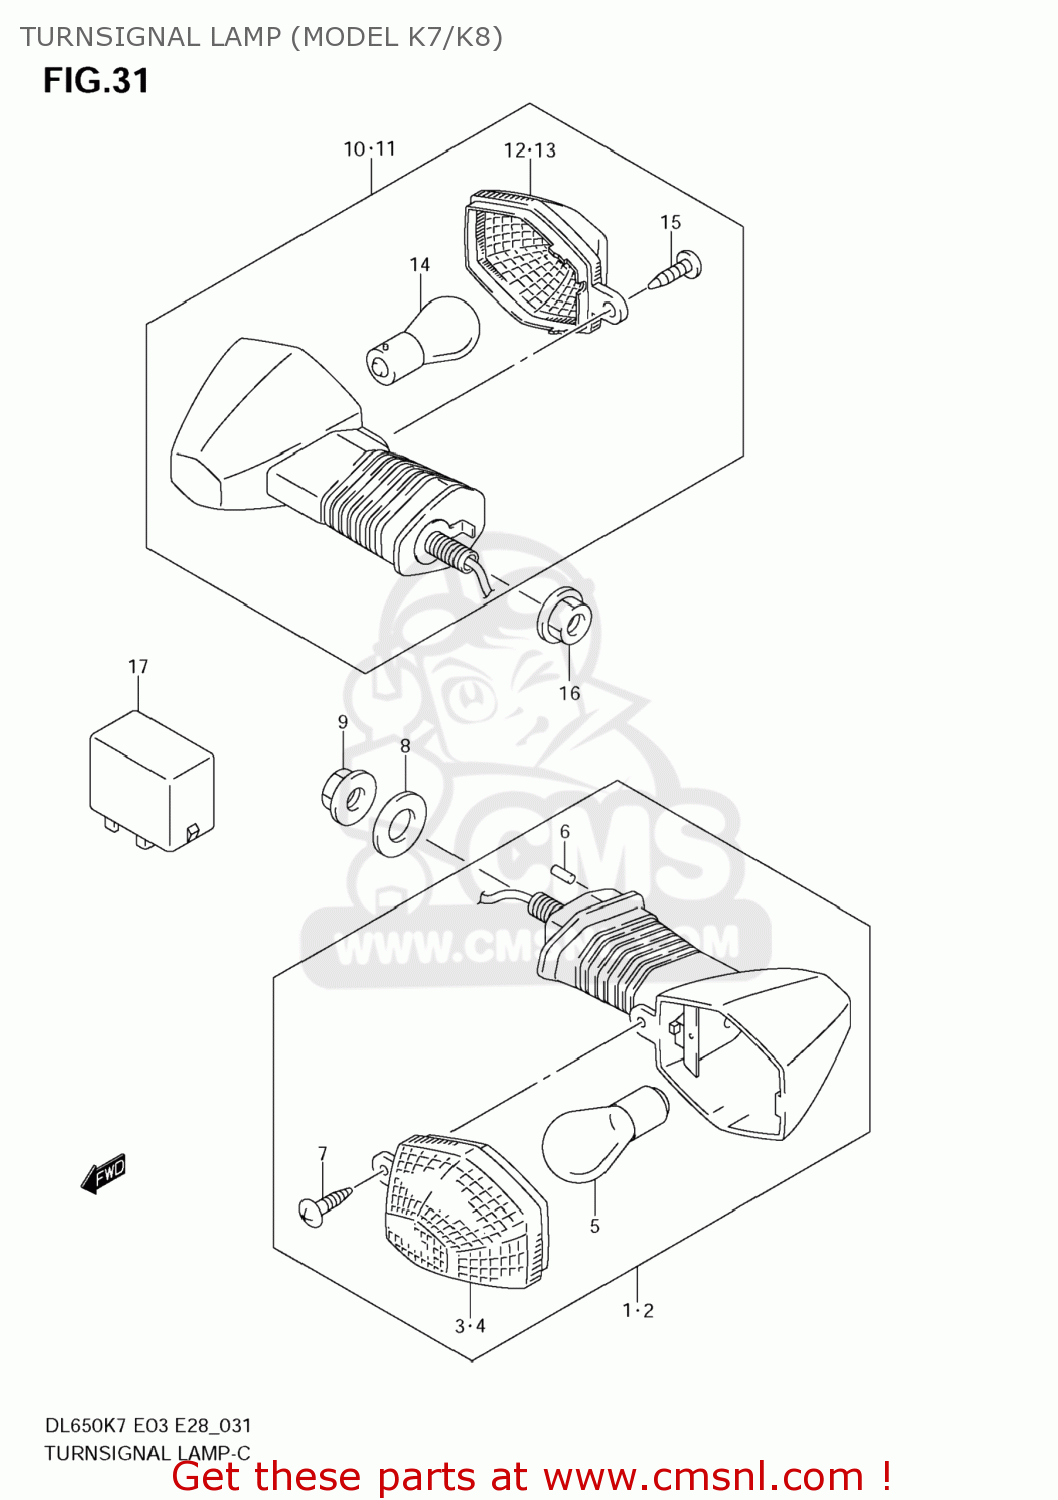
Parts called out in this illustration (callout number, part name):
1	LAMP ASSY,FR TURN SIGNAL,R
2	LAMP ASSY,FR TURN SIGNAL,L
3	LENS
4	LENS
5	BULB(12V21W)
6	PIN(4.5X9.5)
7	SCREW
8	WASHER(12.5X30X1.6)
9	NUT
10	LAMP ASSY,RR TURNSIGNAL,R
11	LAMP ASSY,RR TURNSIGNAL,L
12	LENS
13	LENS
14	BULB(12V21W)
15	SCREW
16	NUT
17	RELAY ASSY,TURNSIGNAL LAMP
